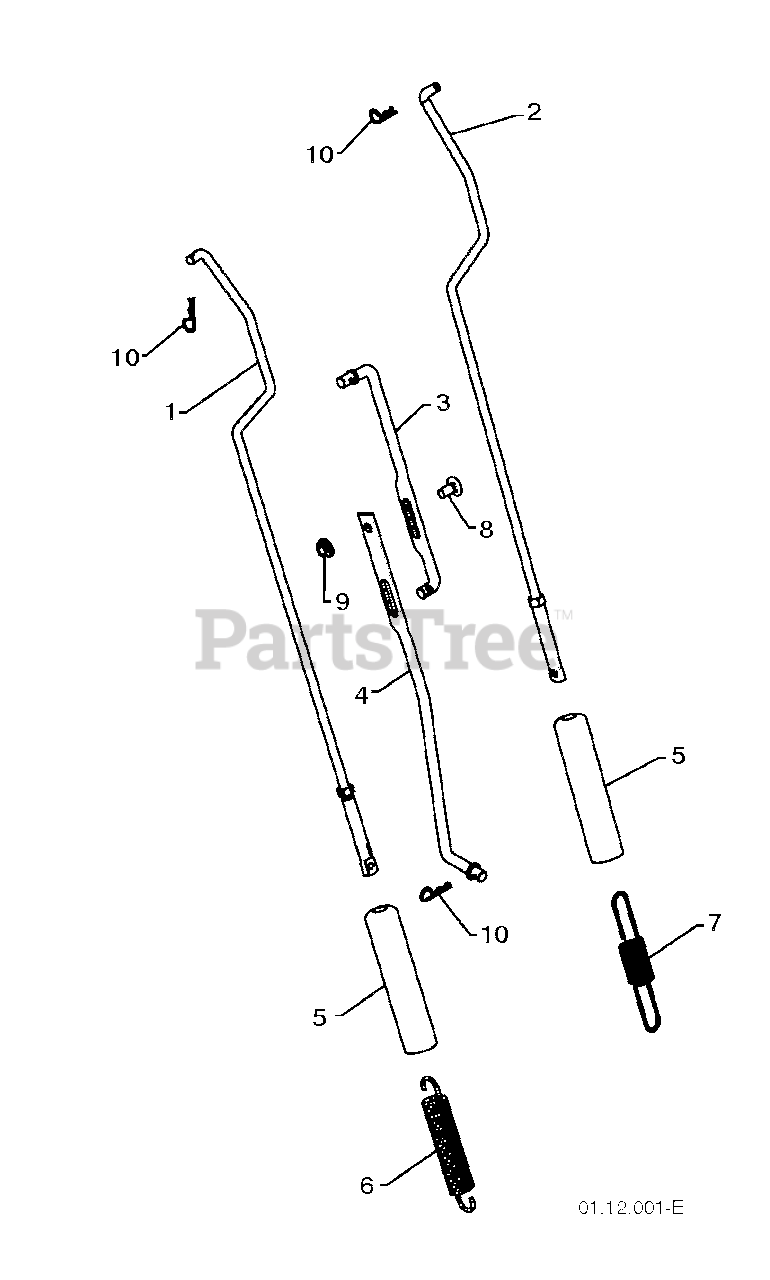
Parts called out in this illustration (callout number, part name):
1	ROD.ASM.IMPELLER
2	ROD.ASM.TRACTION
3	ROD, UPPER SPEED CONTROL
4	ROD, LOWER SPEED CONTROL
5	SLEEVE, SPRING
6	SPRING, AUGER CONTROL
7	SPRING, TRACTION DRIVE
8	BOLT
9	NUT.FLANGE.5/16
10	SPRING RETAINER
